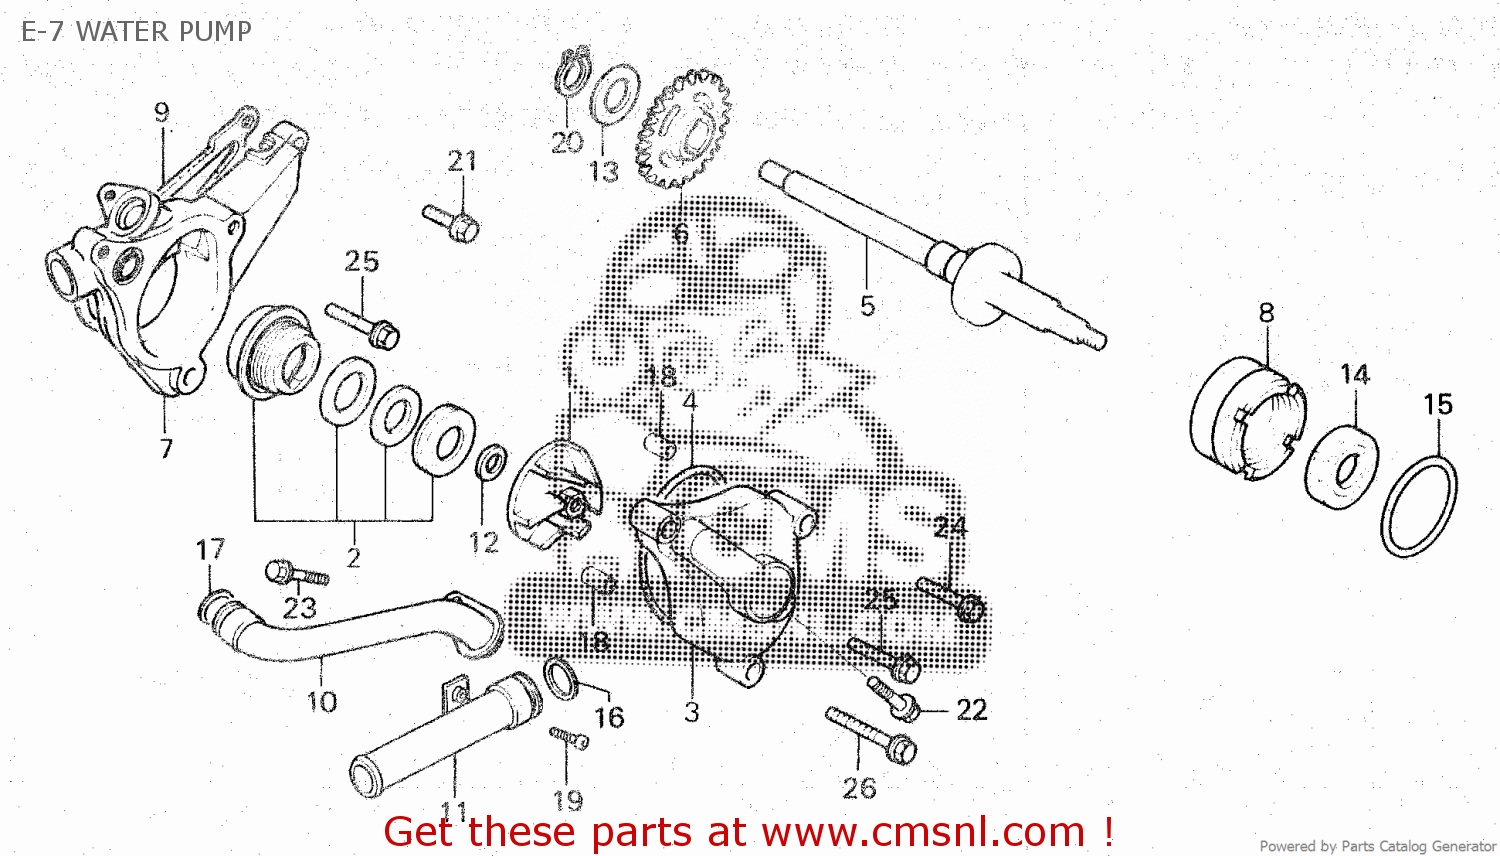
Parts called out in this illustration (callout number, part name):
1	IMPELLER,PUMP
2	SEAL MECHANICAL
3	COVER,MATER PUMP
4	O-RING,WATER PUMP
5	SHAFT,WATER PUMP
6	GEAR,W/PUMP DRIVE
7	BODY,WATER PUMP
8	COLLAR,W/PUMP SEA
9	GSKT,W/PUMP BODY (MCA)
10	PIPE A,WATER
11	PIPE B,WATER
12	WASH,SEALING,7MM
13	WASHER,THRUST
14	OIL SEAL,15X28X7
15	O-RING,35.2X2.5
16	O,RING,16.5X2.5
17	O-RING 18X2.6
18	PIN.DOWEL SPC 8X7
19	SCREW,PAN,5X10
20	CIRCLIP,EX,15
21	BOLT,FLANGE,6X10
22	BOLT,FLANGE,6X12
23	BOLT,FLANGE,6X14
24	BOLT.FLANGE,6X22
25	BOLT,FLANGE,6X25
26	BOLT,FLANGE 6X50
